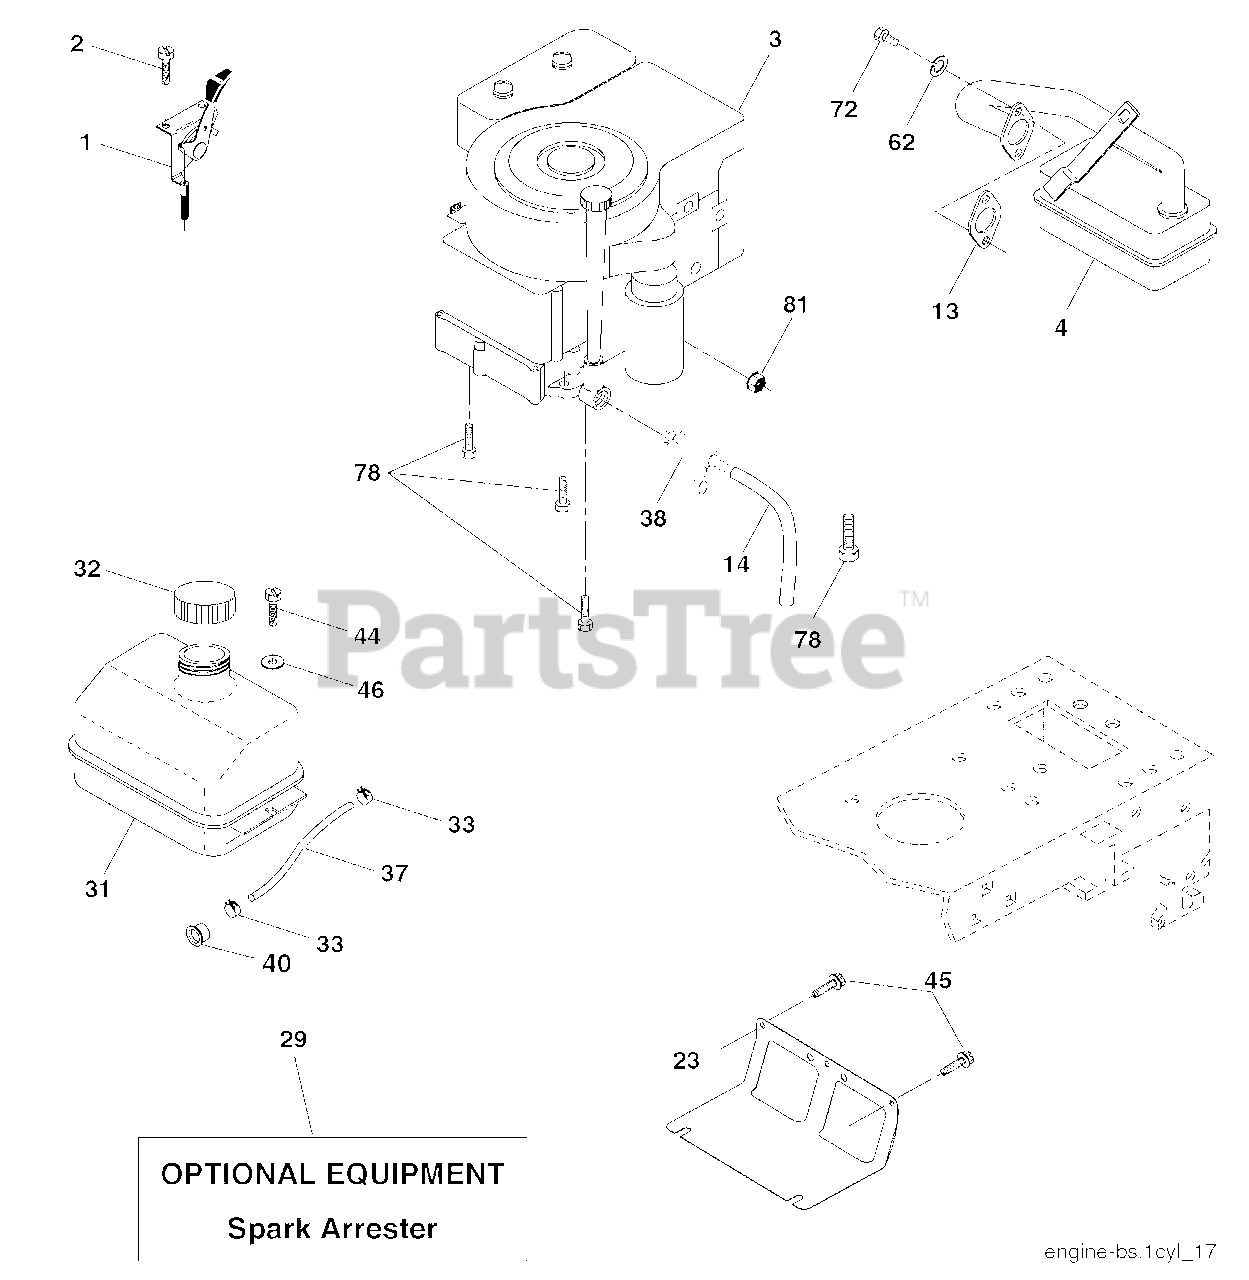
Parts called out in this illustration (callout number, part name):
1	Control Throttle /Choke Flag
2	Screw Hex Thd Cut 1/4-20 x 1/2
4	Muffler Exhaust B&S Lt
13	Gasket 1 313 Id Tin Plated
14	Tube Drain Oileasy
23	Shield Browning/Debris Guard
29	Arrestor Spark
31	Tank Fuel 1 25 Fr
32	Cap Asm Fuel
33	Clamp Hose Blk
37	Line Fuel 20”
38	Plug Drain Oileasy
40	Bushing Snap Nyl Blk Fuel Line
44	Screw Hexwsh Thdrol 1/4-20 x 3/4
45	Screw Hex Wsh Thdrol 3/8-16
46	Washer 9/32 x 7/8 x 16 Ga.
62	Washer Split
72	Screw Socket Head 5/16-18 x .75
78	Screw Thdrol 3/8-16 x 1-1/4
81	Nut Keps Hex 1/4-20 unc
